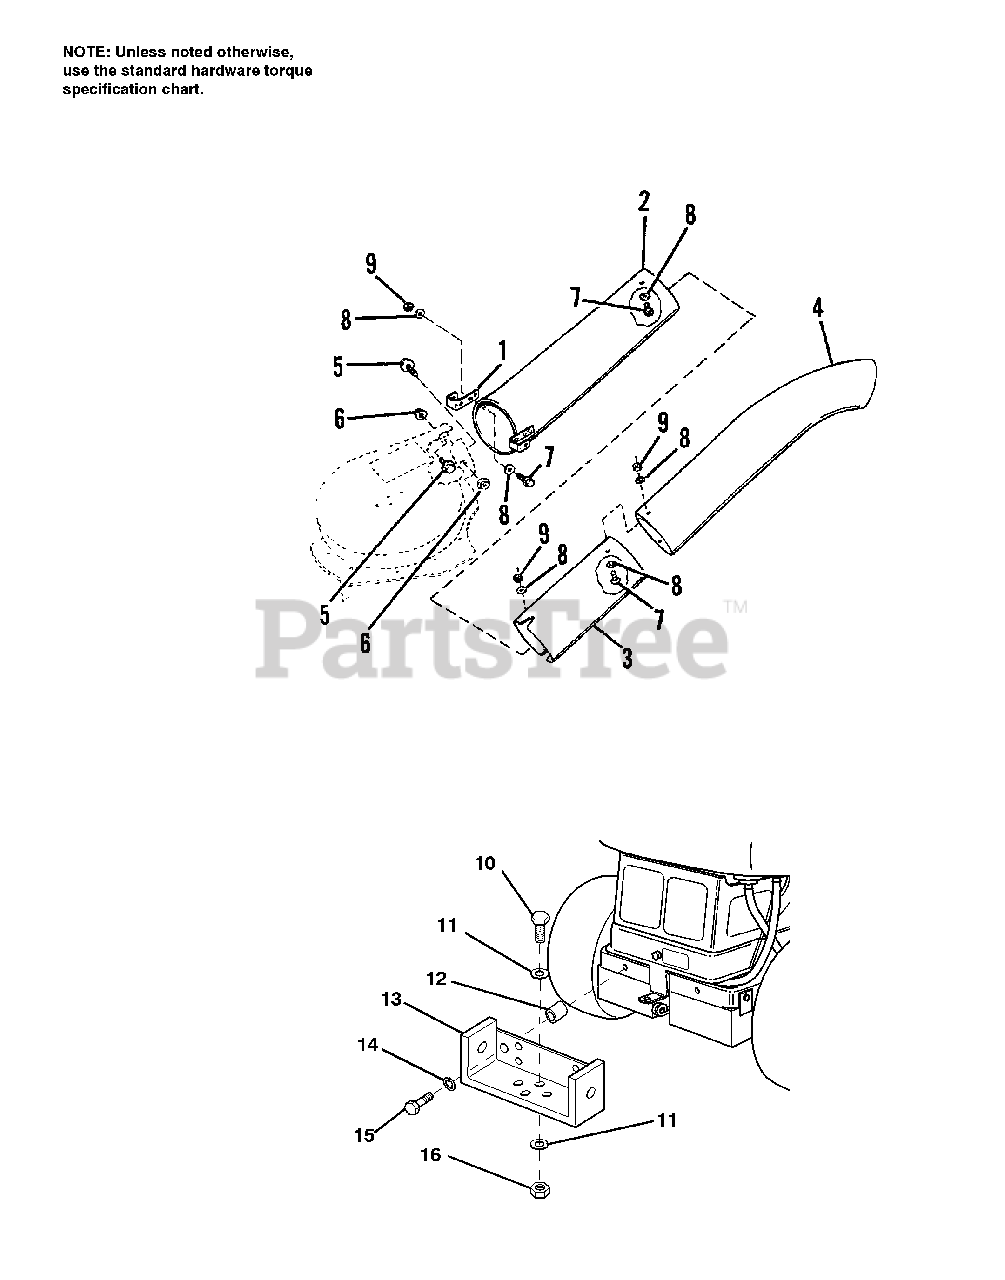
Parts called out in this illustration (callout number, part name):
1	CLIP, Spring
2	TUBE ASSY, Lower
3	TUBE ASSY, Middle
4	TUBE ASSY, Upper
5	CARRIAGE BOLT, 1/4-20 x 5/8
6	LOCKNUT, Flange, 1/4-20
7	SCREW, Truss Head, 10-32 x 1/2
8	WASHER, Plain, #10
9	NUT & WASHER ASSY, 10-32
10	Capscrew, 3/8-16 x 1
11	Flat Washer, 3/6
13	Hitch
14	Lockwasher, 3/8
15	Capscrew, 3/8-16 x 2-1/4
16	Hex Nut, 3/8-16
